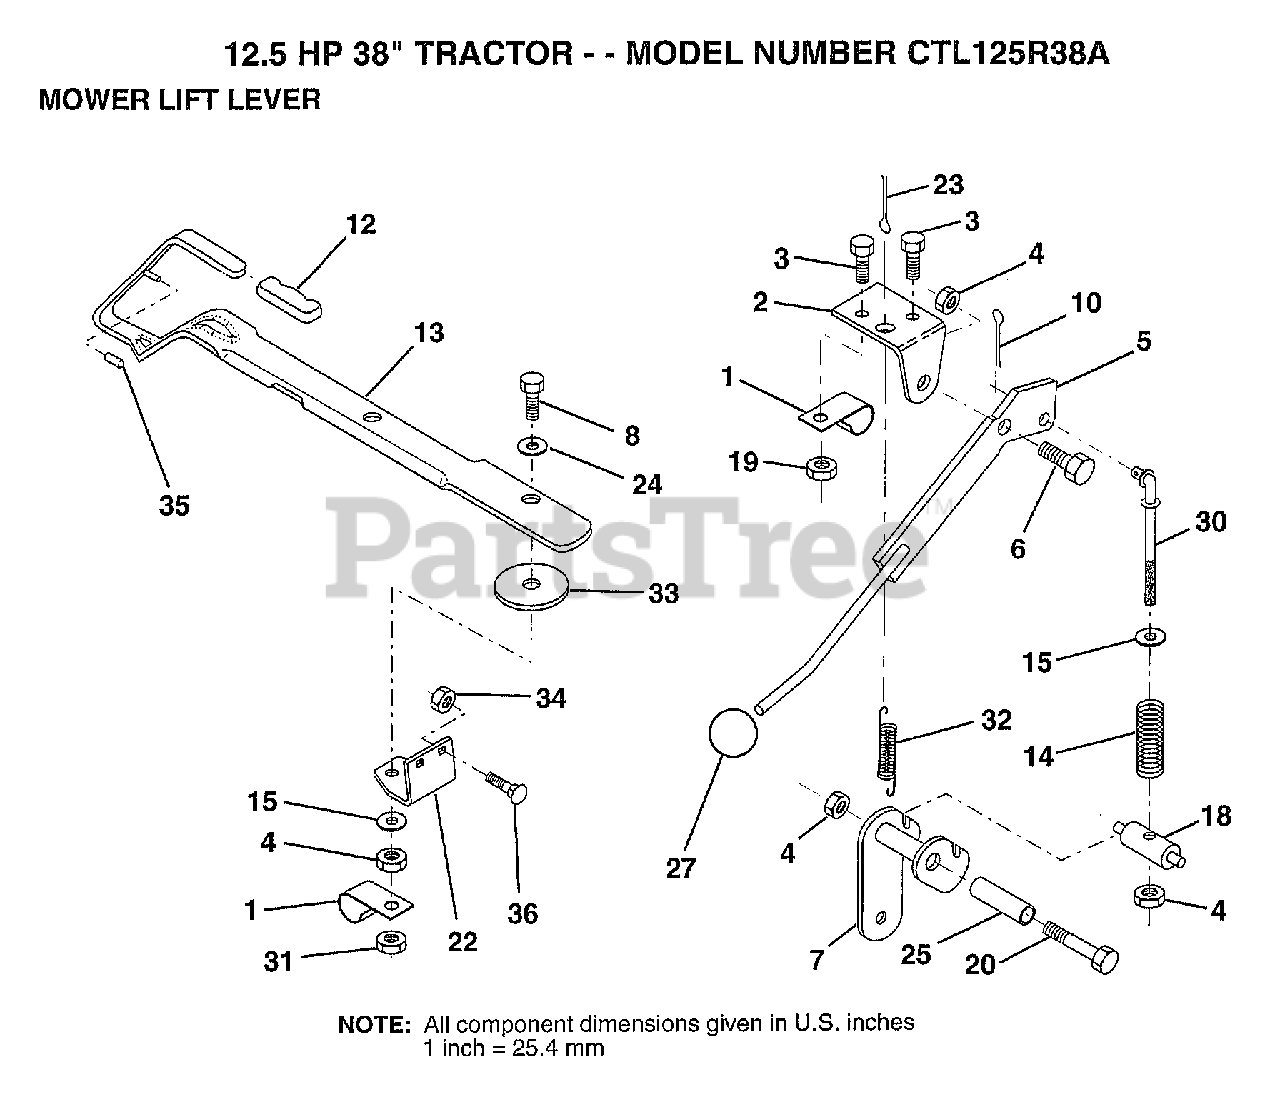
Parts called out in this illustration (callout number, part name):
1	"CLIP,INSULATOR"
2	BRKT CLUTCH
3	BOLT
5	CLUTCH LEVER AS
6	"BOLT, SHOULDER LT"
7	MWR CLUT ARM ASM
8	BOLT
10	COTTER PIN
12	GRIP HANDLE
13	LEVER LIFT LR
14	COMP CLUTCH SPRNG
15	WASHER HYT
18	TRUNNION
20	BOLT
22	LIFT LEVER BRKT
24	WASHER
25	TUBE SPACER
27	KNOB
30	ROD TENSION CLUTC
31	LOCKNUT
32	SPRING EXT
33	WASHER
35	VINYL CAP RED
36	BOLT
